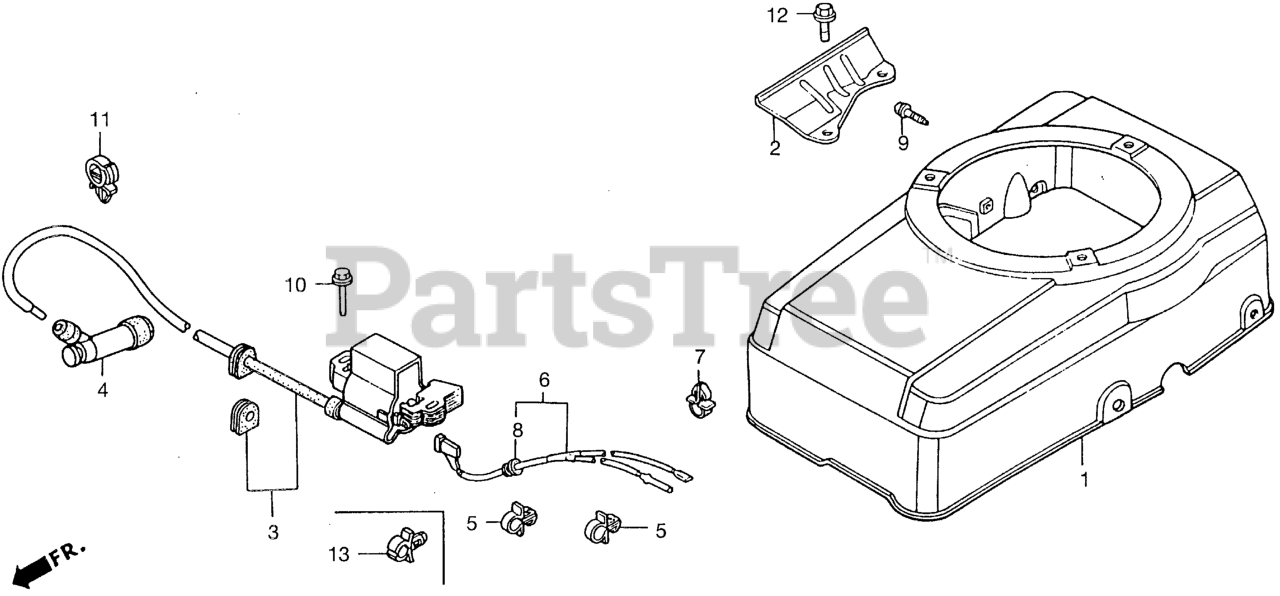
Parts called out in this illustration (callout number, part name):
1	COVER, FAN *R8* (BRIGHT RED)
1	COVER, FAN *R8* (Honda Code 4542494). (BRIGHT RED)
2	PLATE, SIDE
3	COIL ASSY., IGNITION
4	CAP ASSY., NOISE SUPPRESSOR
5	CLIP, IGNITION WIRE (8MM)
6	WIRE, STOP SWITCH
7	HOLDER, STOP SWITCH WIRE Use up to Engine SN 2056819.
8	GROMMET, WIRE
9	BOLT, FLANGE (6X12) (CT200)
10	BOLT, FLANGE (6X28) (CT200) Use up to Engine SN 1530314.
11	CLIP, WIRE HARNESS
12	BOLT, FLANGE (8X20)
13	CLIP, BRAKE PIPE (A) (FOR NEUTRAL SWITCH)
